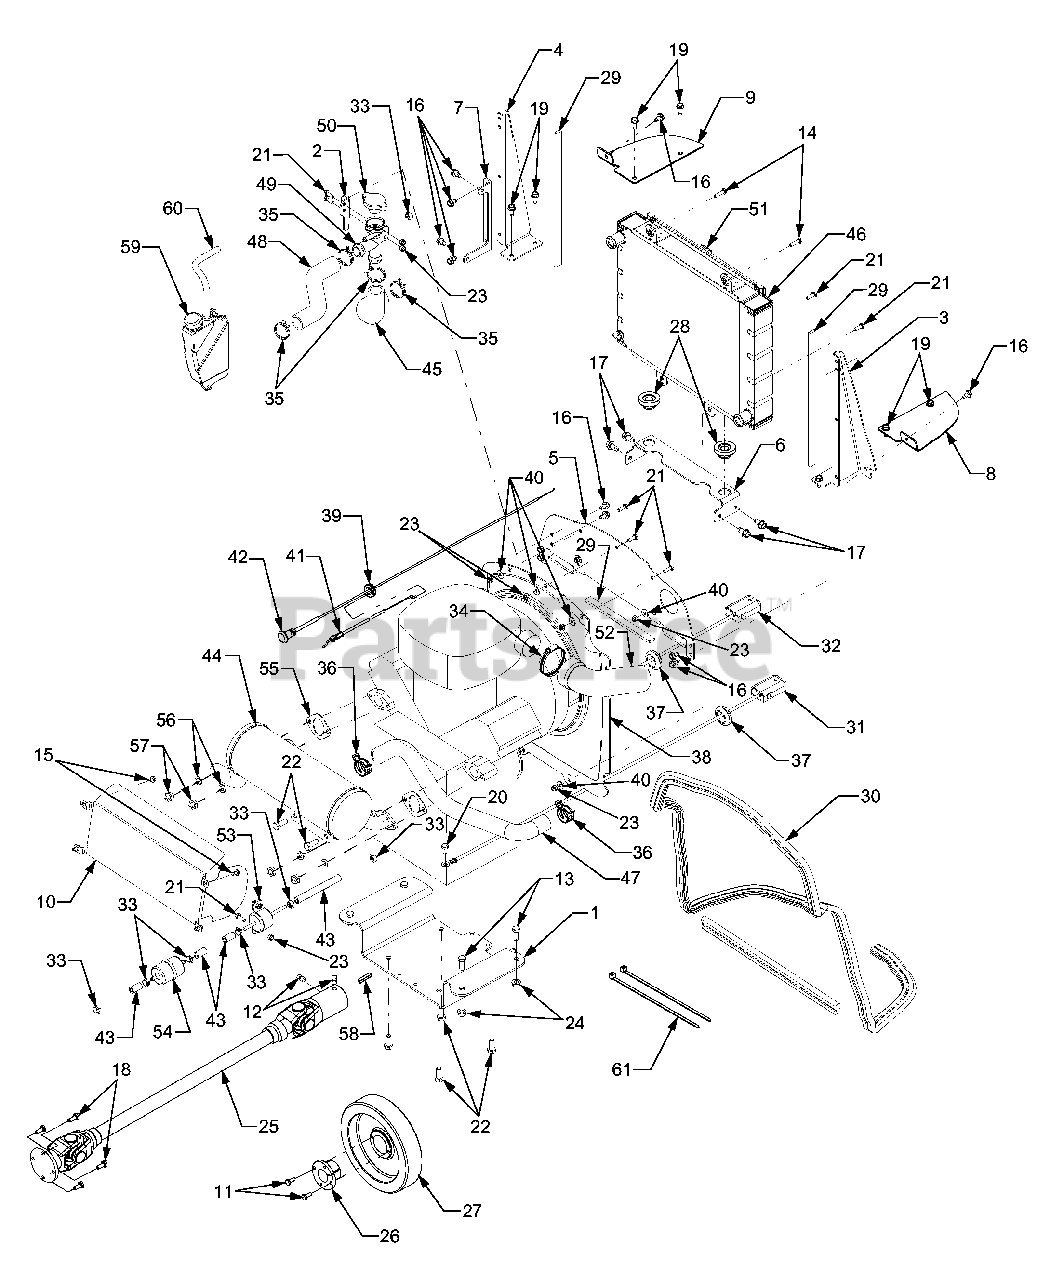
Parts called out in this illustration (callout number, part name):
3	Bracket, Radiator Mtg. RH
4	Bracket, Radiator Mtg. LH .
5	Plate, Radiator Baffle
6	Bracket, Radiator Mtg.
7	Bracket, Ovrflw Bottle Mtg.
8	Plate, Baffle RH
9	Plate, Baffle LH
10	Shield, Heat
11	Screw, Hex Cap, 1/4-28 x .625 GR5
12	Screw, Square Hd. Set, 3/8-16
13	Screw, Hex Cap, 3/8-16 x 1.0 GR5
14	Screw, Hex Cap, 1/4-20 x 1.0 GR5
15	Screw, Hex Wash Hd Tapp 1/4-20 x .5
16	Screw, Hex Wash Hd Tapp 5/16-18 x .5
17	Screw, Hex Wash Hd Tapp 3/8-16 x .75
18	Screw, Hex Cap, 1/4-20 x .62 GR5
19	Screw, Hex Wash Hd Tapp 5/16-18 x .75
20	Screw, Hex Cap, M8-20 x 16 GR8.8
21	Screw, Hex Cap, 1/4-20 x .75 GR5
22	Screw, Hex Cap, M10 x 1.5 x 25 GR5
23	Nut, Hex Nylon Insert Lock 1/4-20 GR8
24	Nut, Hx Flnge Lock, 3/8-16
25	Shaft, Drive
26	Bushing, D Type
27	Flywheel
28	Grommet, Rubber
29	Tape, Foam, .625 wide 42in.
30	Seal, Heat Baffle 103in.
31	Wire, Battery Neg.
32	Wire, Battery Pos.
33	Clamp, Hose
34	Clamp, Hose - Adjustable .
35	Clamp, Hose
36	Clamp, Hose
38	Shroud, Fan
40	Washer, Flat, .28 x .74 x .063
41	Cable, Throttle
42	Cable, Choke Control
43	Fuel Line 5/16 ID 92in.
45	Hose, Filler to Radiator
47	Hose, Lower Radiator
48	Hose, Engine to Filler Neck
49	Filler Neck, Remote Radiator
50	Cap, Remote Filler
51	Screen, Radiator
52	Hose, Intake Air
54	Filter, Fuel
55	Gasket, Exhaust
56	Washer, Spring
58	Key, Crankshaft
59	Bottle, Over Flow
61	Tie, Cable
